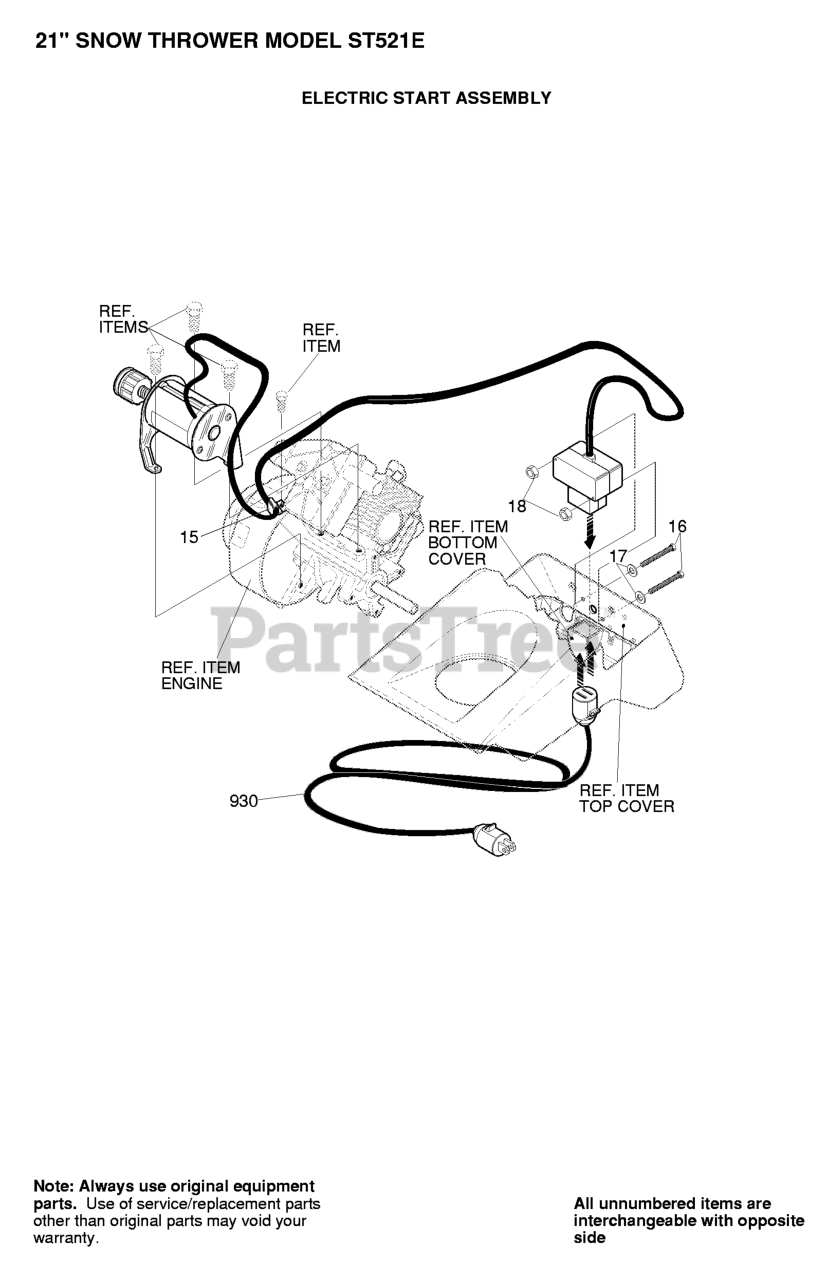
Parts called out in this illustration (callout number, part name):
15	RETAINER, .31IDX.62X.03 W
17	WASHER, FLAT .188X .38X.
930	EXTENSION CORD, 10 FT
